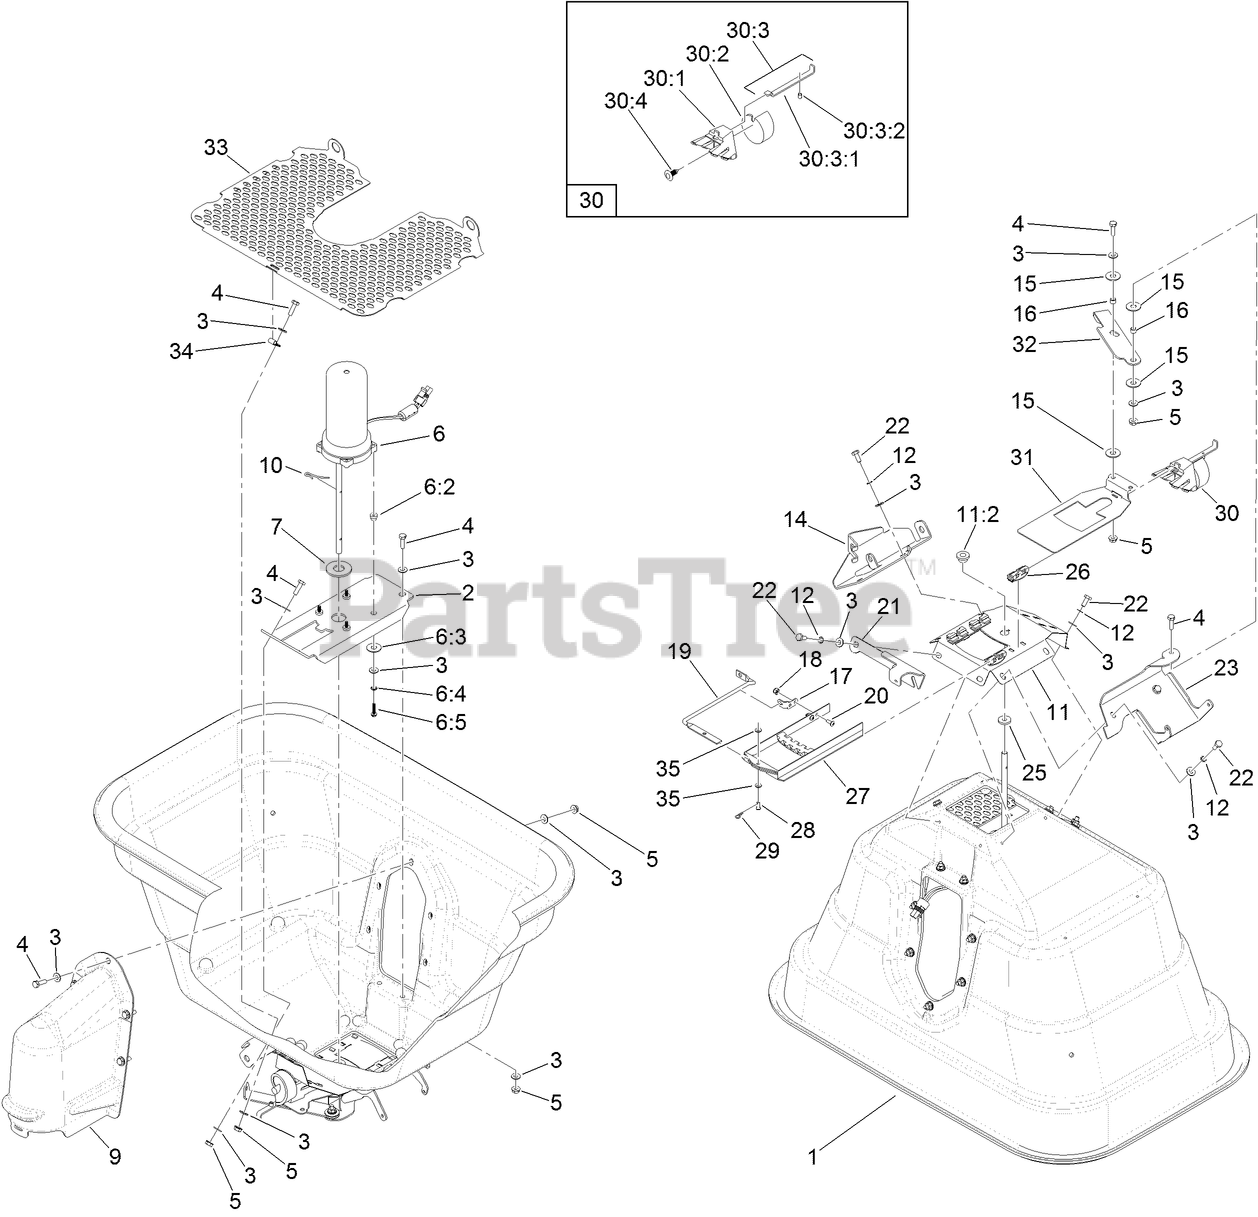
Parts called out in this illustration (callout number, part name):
1	HOPPER-SPREADER
2	BRACKET-MOUNT, MOTOR
3	WASHER-FLAT
4	SCREW-HH
5	NUT-HF
6	SPREADER MOTOR ASM
6:2	SPACER-FLANGED
6:3	WASHER-FLAT
6:4	WASHER-LOCK, INT
6:5	SCREW-SHWH
7	SPACER
9	COVER-MOTOR
10	AGITATOR
11	MULCH PLATE W/ BEARING ASM
11:2	BEARING-BOTTOM, HOPPER
12	WASHER-LOCK, INT
14	BRACKET-HOPPER, GATE CONTROLS
15	WASHER
16	SPACER
17	BRACKET-DIFFUSER
18	NUT-HEX
19	ROD-CONTROL, DIFFUSER
20	SCREW-PPH
21	BRACKET-SPRING, HOPPER DEFLECTOR
22	SCREW-HH
23	BRACKET-LEVER, HOPPER GATE
25	WASHER-FELT
26	GUIDE-RATE, GATE
27	DIFFUSER
28	PIN-CLEVIS
29	PIN-COTTER, HAIR
30	RATE DIAL ASM
30:1	MOUNT-DIAL
30:2	DIAL
30:3	RATE GATE LINK ASM
30:3:1	LINK-GATE, RATE
30:3:2	SCREW-SHOULDER, SLOTTED
30:4	CLIP
31	GATE-RATE
32	LEVER-GATE
33	SCREEN-HOPPER-LARGE HOLE
33	SCREEN-HOPPER-MEDIUM HOLE
33	SCREEN-HOPPER-SMALL HOLE
34	CLAMP-LOOP
35	WASHER-FLAT
